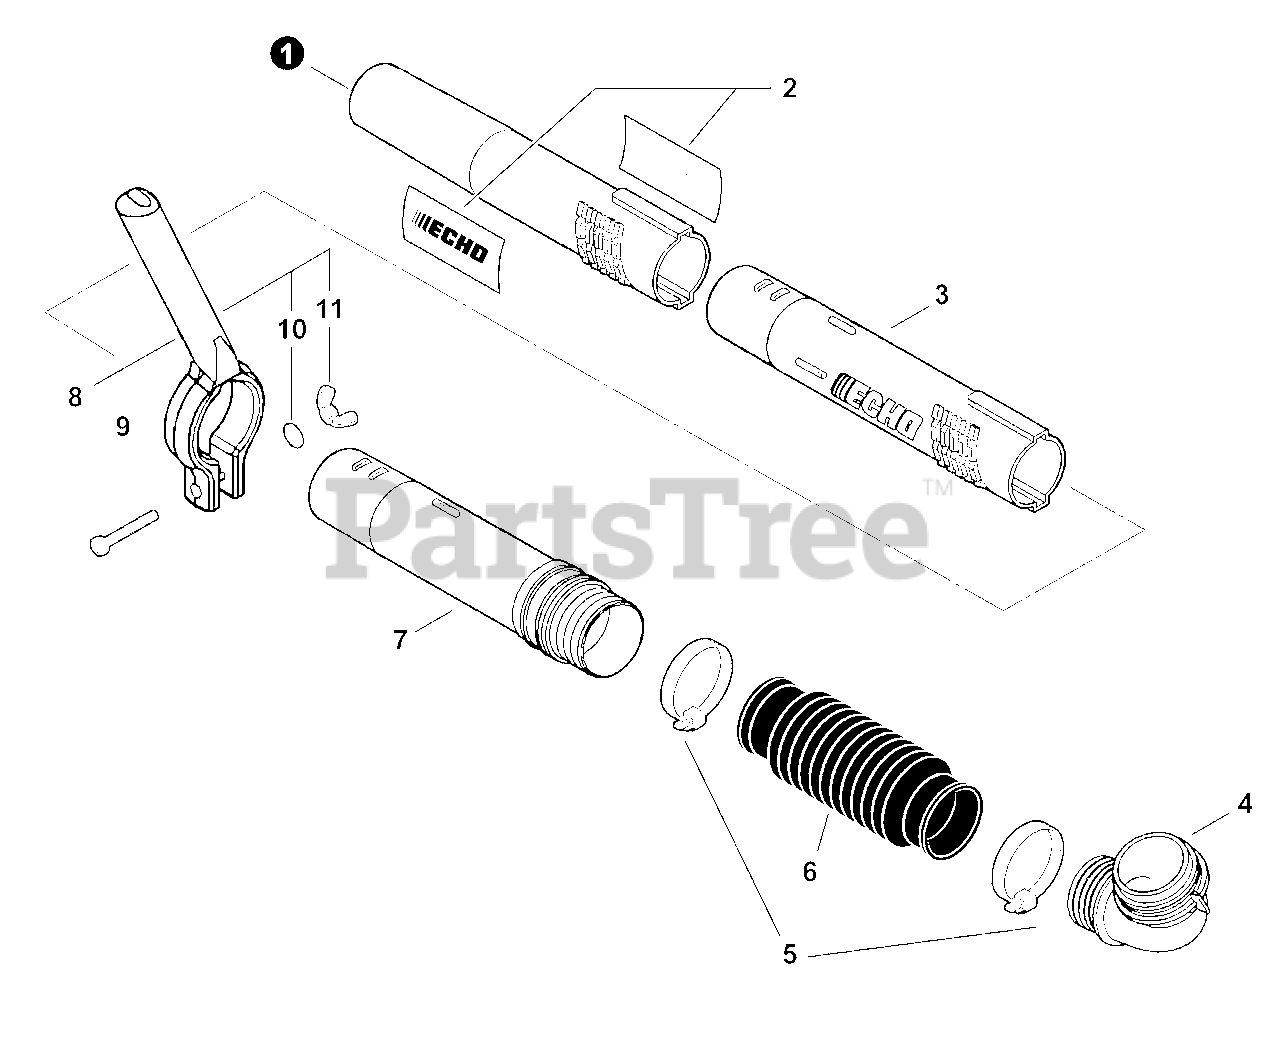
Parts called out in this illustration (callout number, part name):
1	TUBE, BLOWER - STRAIGHT NOZZLE
2	LABEL - ECHO
3	TUBE, BLOWER - STRAIGHT
4	TUBE, BLOWER - ELBOW
5	CLAMP, HOSE
6	TUBE, BLOWER - FLEXIBLE
7	TUBE, BLOWER - SWIVEL
8	TUBE MOUNT HANDLE
9	BOLT - 6×45
10	WASHER - 6
11	WINGNUT - 6
